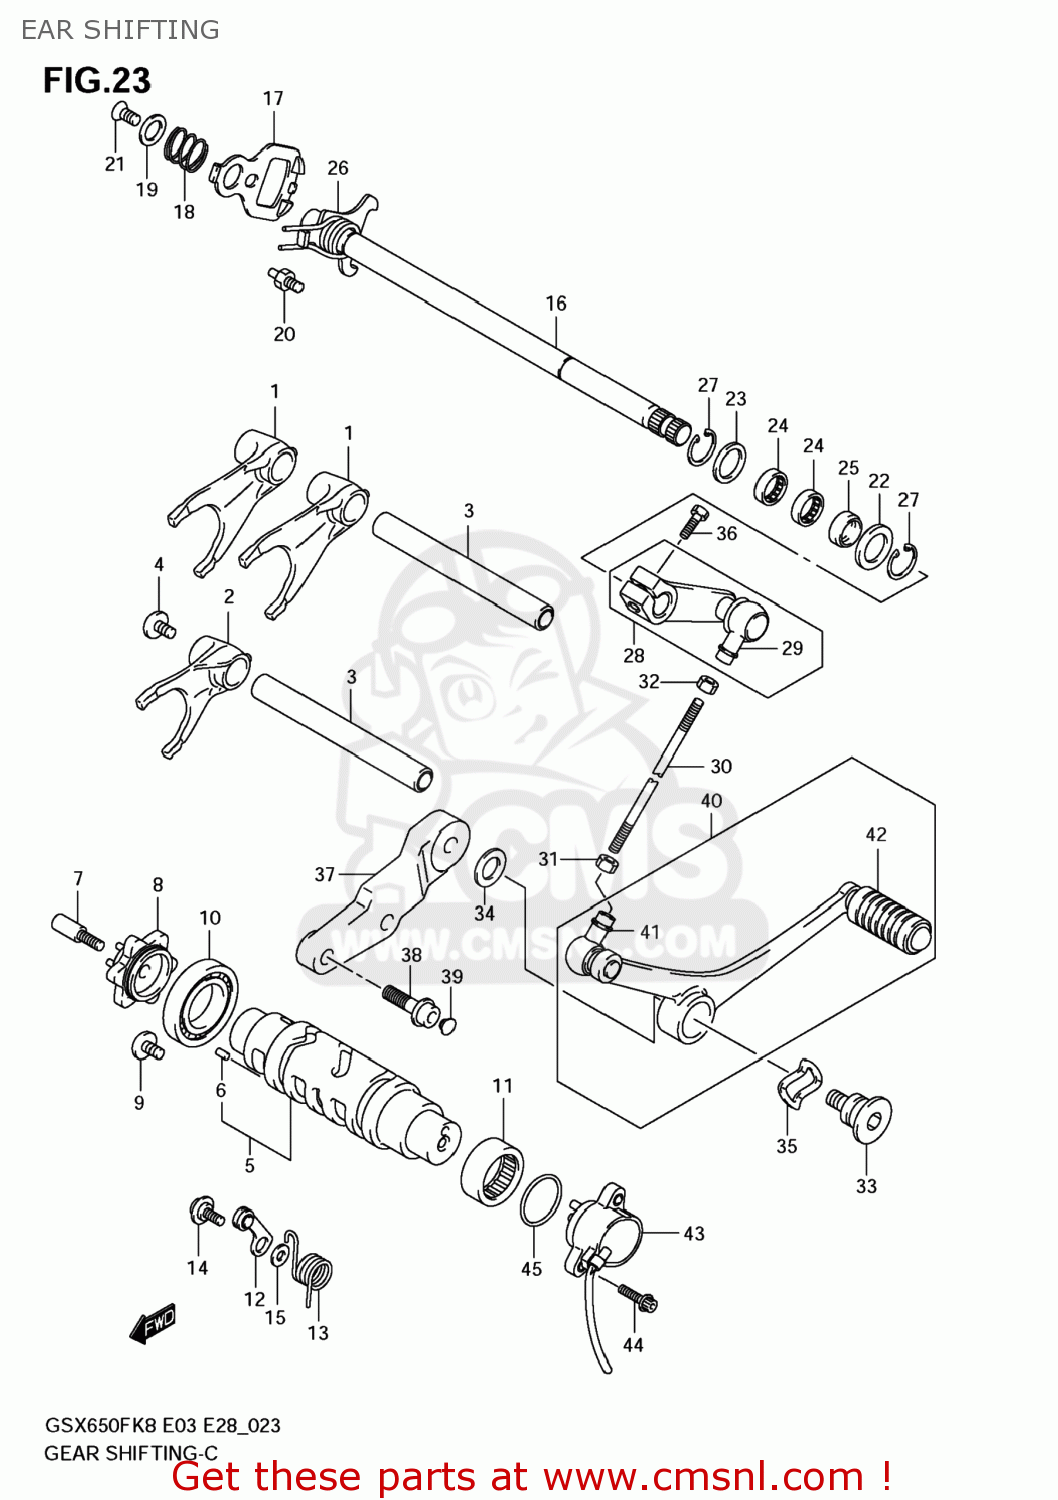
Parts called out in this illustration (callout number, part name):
1	NUT
2	NUT
3	SHIM(14X24X1)
4	BOLT(5X16)
5	WASHER
6	PIN
7	CIRCLIP
8	BOLT(8X28)
9	COVER,DUST
